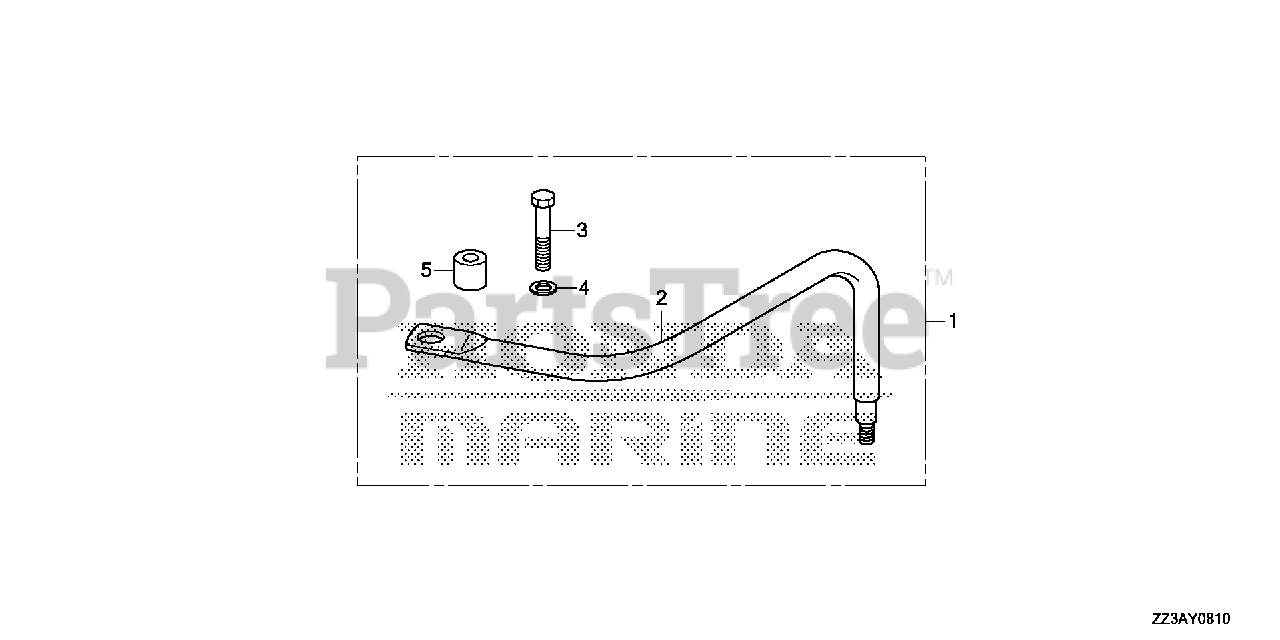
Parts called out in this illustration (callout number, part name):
1	ROD KIT, STEERING
2	ROD, STEERING
3	BOLT, HEX. (6X35)
4	WASHER, PLAIN (6MM)
5	COLLAR, DISTANCE (6.5X16X16.5)
